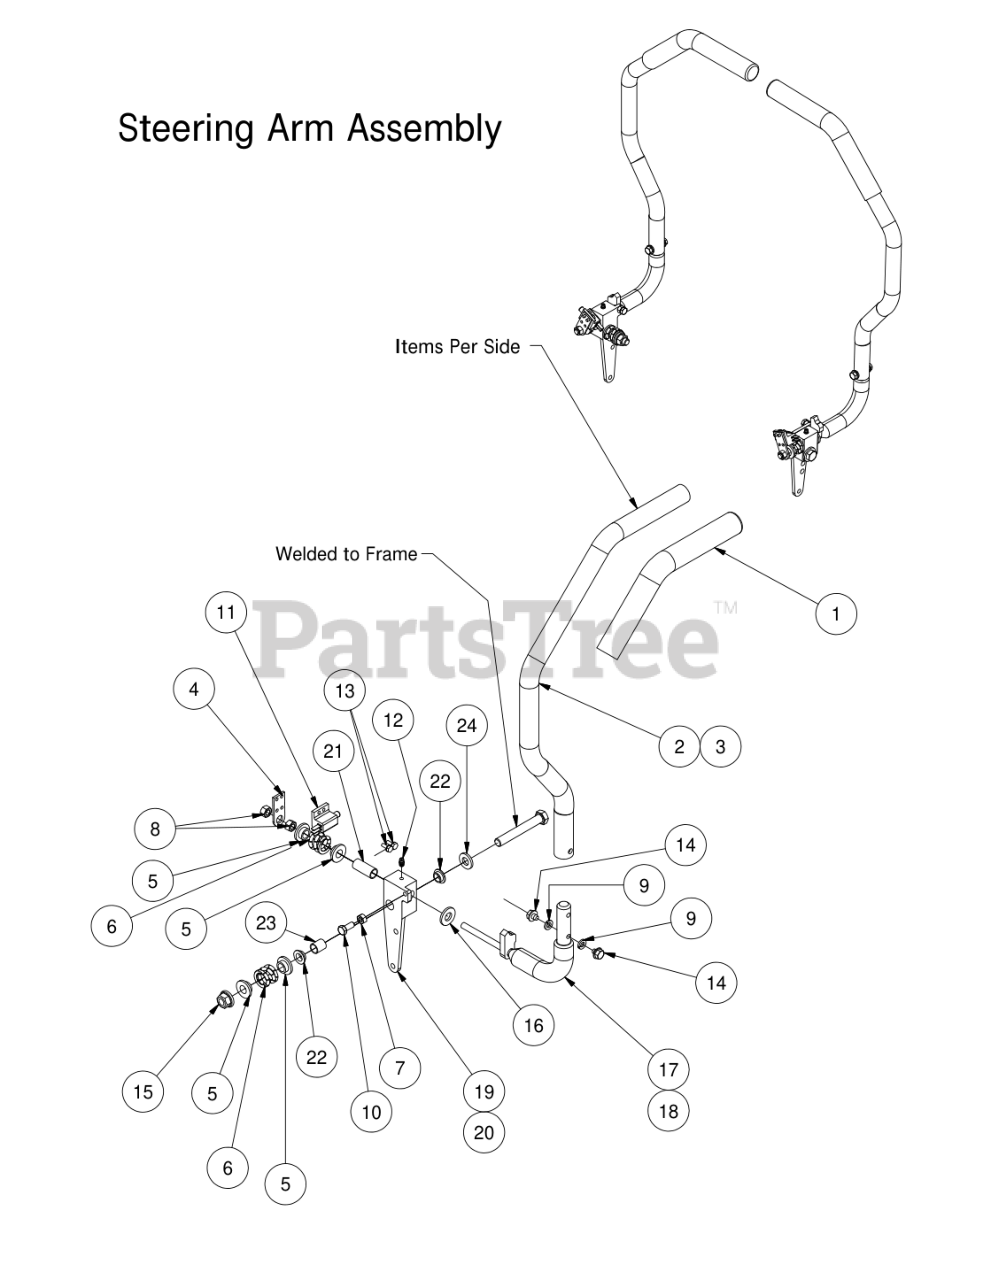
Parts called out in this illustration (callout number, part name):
1	Rubber Grip
2	Left Direction Steering Arm
3	Right Direction Steering Arm
4	MZ Switch Bracket
5	.515 ID Nylon Shoulder Washer
6	Drive Lever Spring
8	1/2" - 13 Nylon Insert Jam Locknut
9	5/16" Lock Washer
10	5/16" x 3/4" Hex Bolt
11	Safety Switch
12	1/4" Press in Grease Fitting
13	12-24x 1/2 HWH Bolt
14	5/16-18 1/2 HWH Bolt-Steering
15	1/2-13 Mechanical Lock Nut Grade F
16	.505 Nylon Spacer
17	Black Steering Arm Elbow (Right)
18	Black Steering Arm Elbow (Left)
19	Left Drive Arm Lever Housing
20	Right Drive Arm Lever Housing
21	Drive Arm Block Insert-long
22	Bushing for 2012 Drive Arms
23	Drive Arm Block Insert-short
24	.505x1x .125 Oil Impregnated washer
